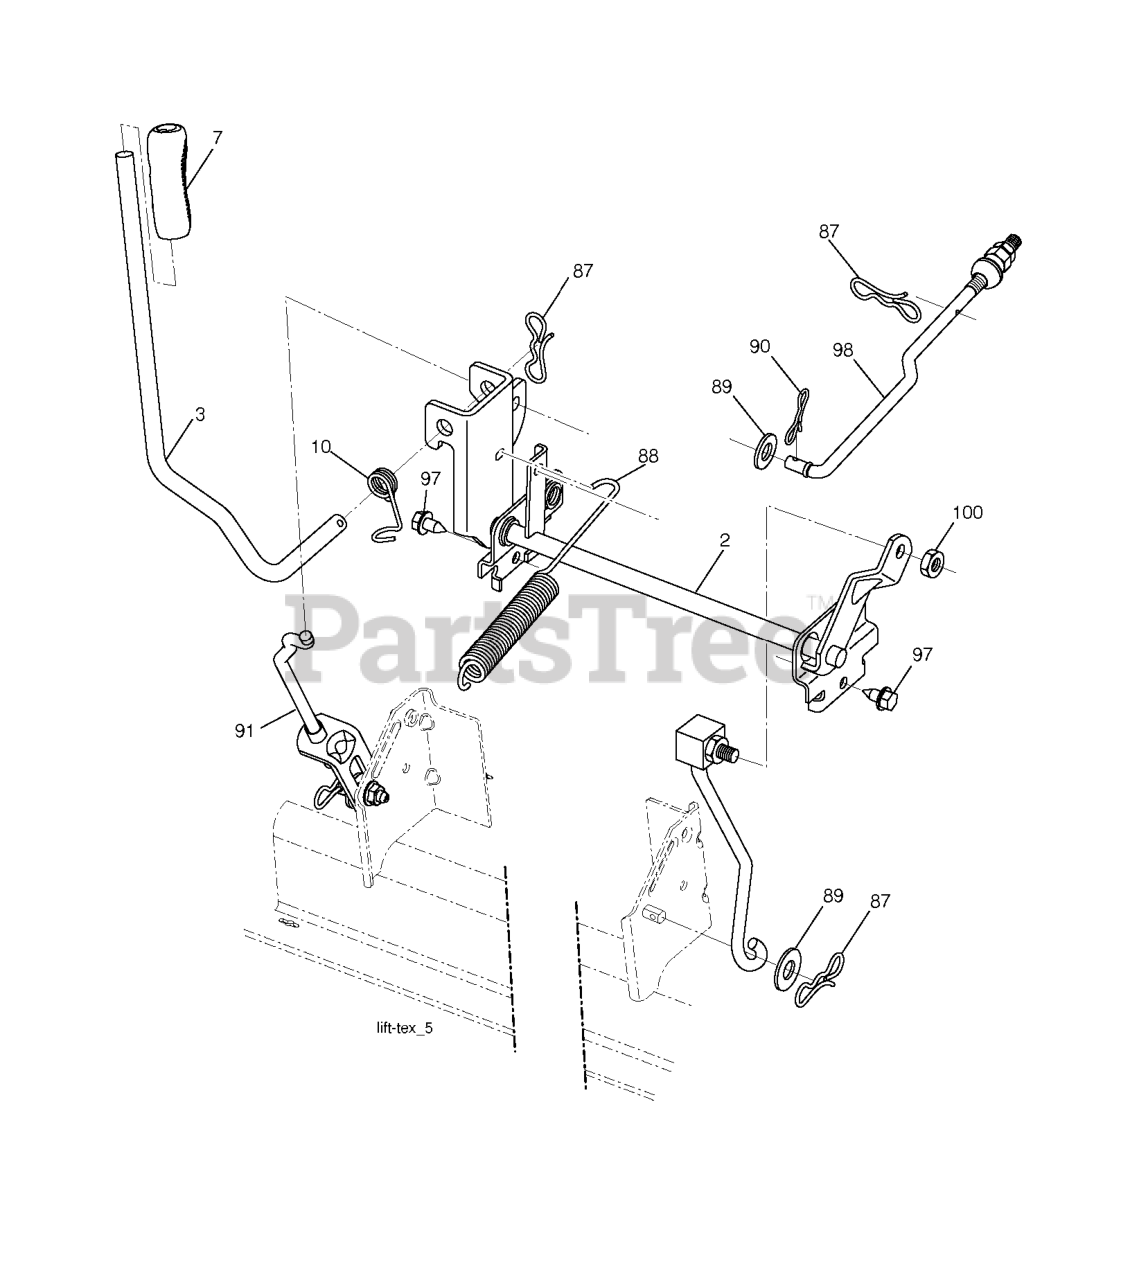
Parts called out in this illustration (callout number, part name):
2	SHAFT.ASM.LIFT.CROSS.H
3	LEVER.LIFT.HANDLE.GT
7	GRIP.HANDLE.LIFT.PVC.BLACK
10	SPRING.TORSION.LIFT.HANDLE
87	PIN.COTTER.7/16.BOW TI.
88	SPRING.LIFT.ASSIST
89	WASHER.CLEAR.ZINC
90	PIN.COTTER.5/16.BOW TI
91	LINK.ASM.LIFT.REAR
97	SCREW, 3/8-16X3/4
98	LINK.ASM.SUSP.FRONT.MW
100	LOCKNUT
